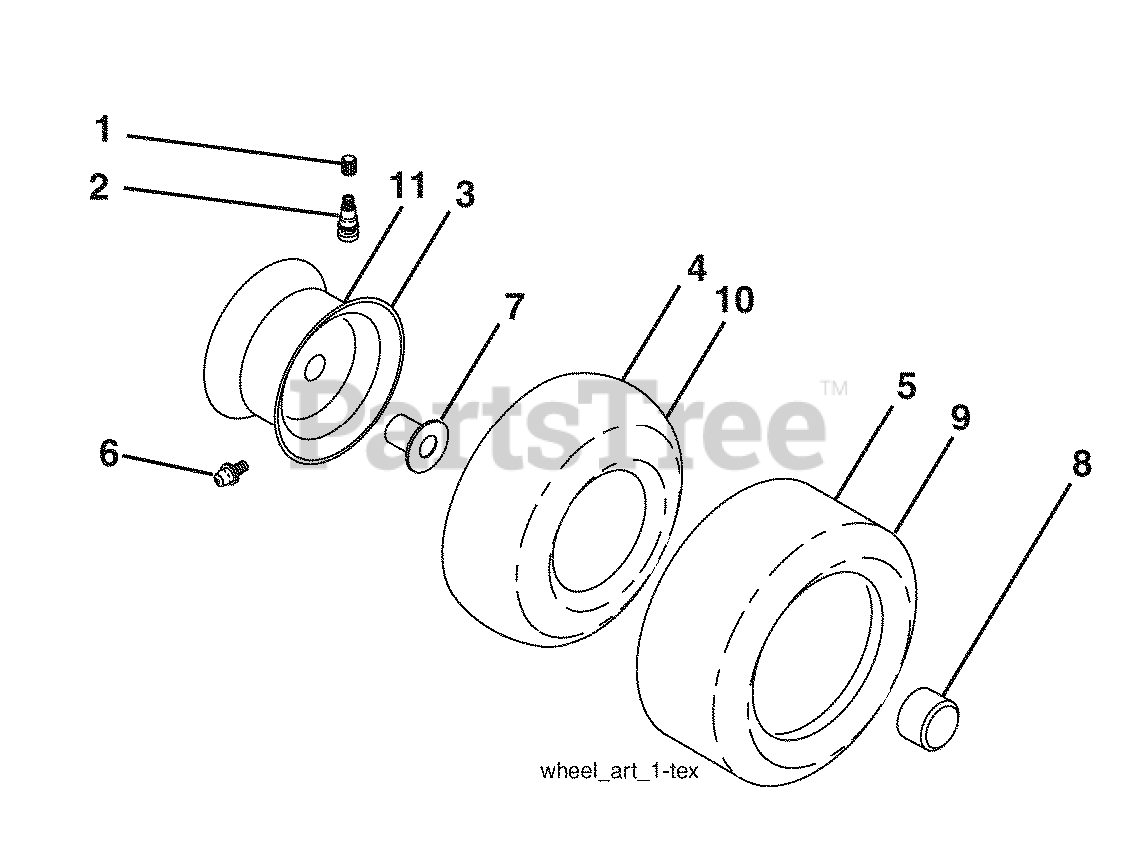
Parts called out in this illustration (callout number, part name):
2	VALVE STEM LT
3	RIM ASM 6" FRONT SILVER
4	TUBE.5.3/4.5/6
5	TIRE.15X6-6.TURF.MASTER.FRONT
6	FITTING LT
7	BEARING T
8	CAP, AXLE BLK
9	TIRE.20X10-8.TURF.MASTER.REAR
10	TUBE
11	RIM ASM 8" REAR SILVER
